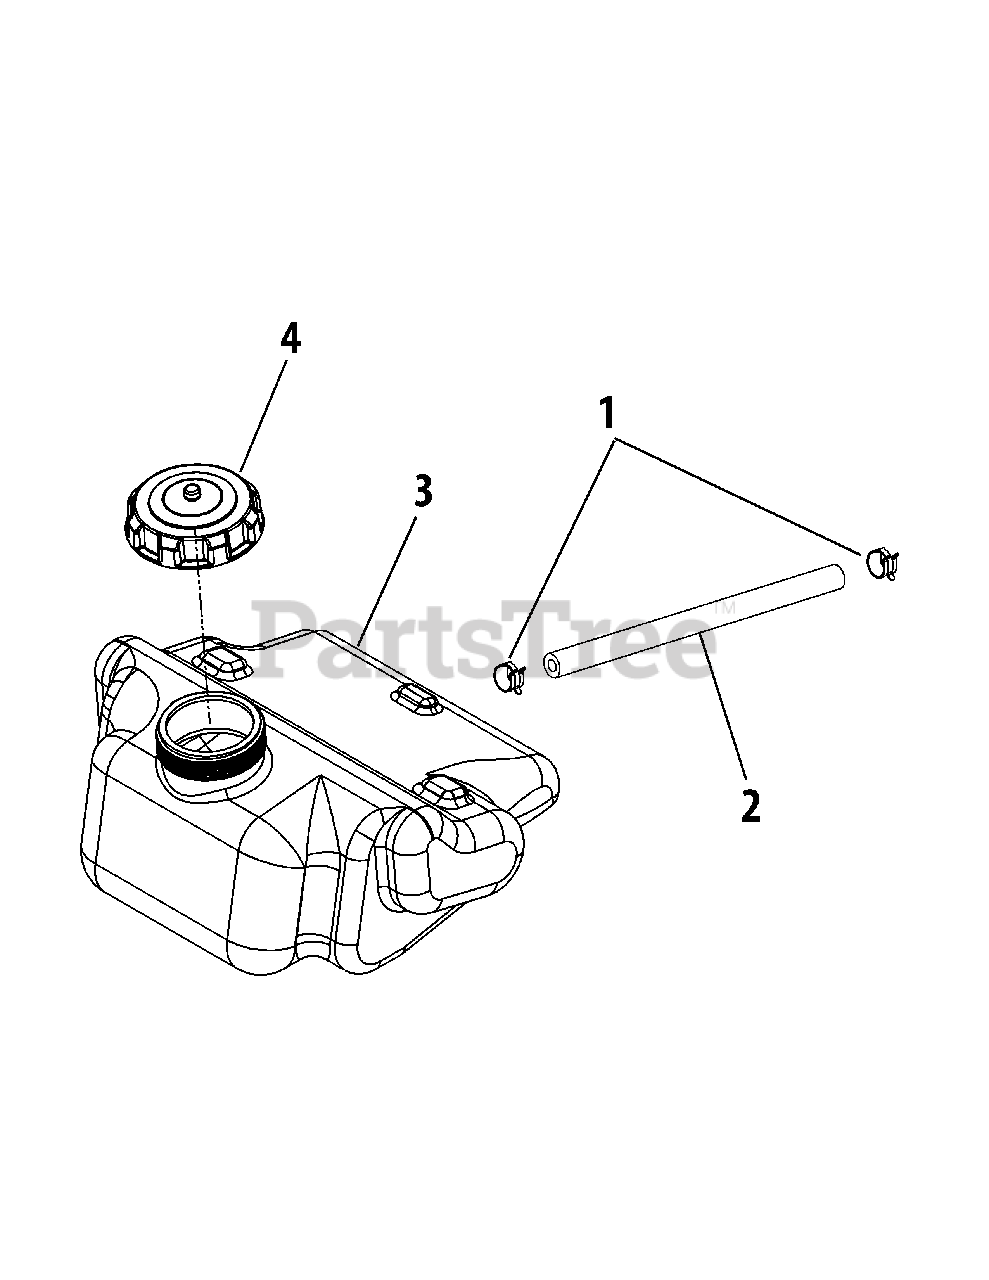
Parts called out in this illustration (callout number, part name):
1	Clamp, Hose
2	Line, Fuel, 51"
3	Tank, Fuel
